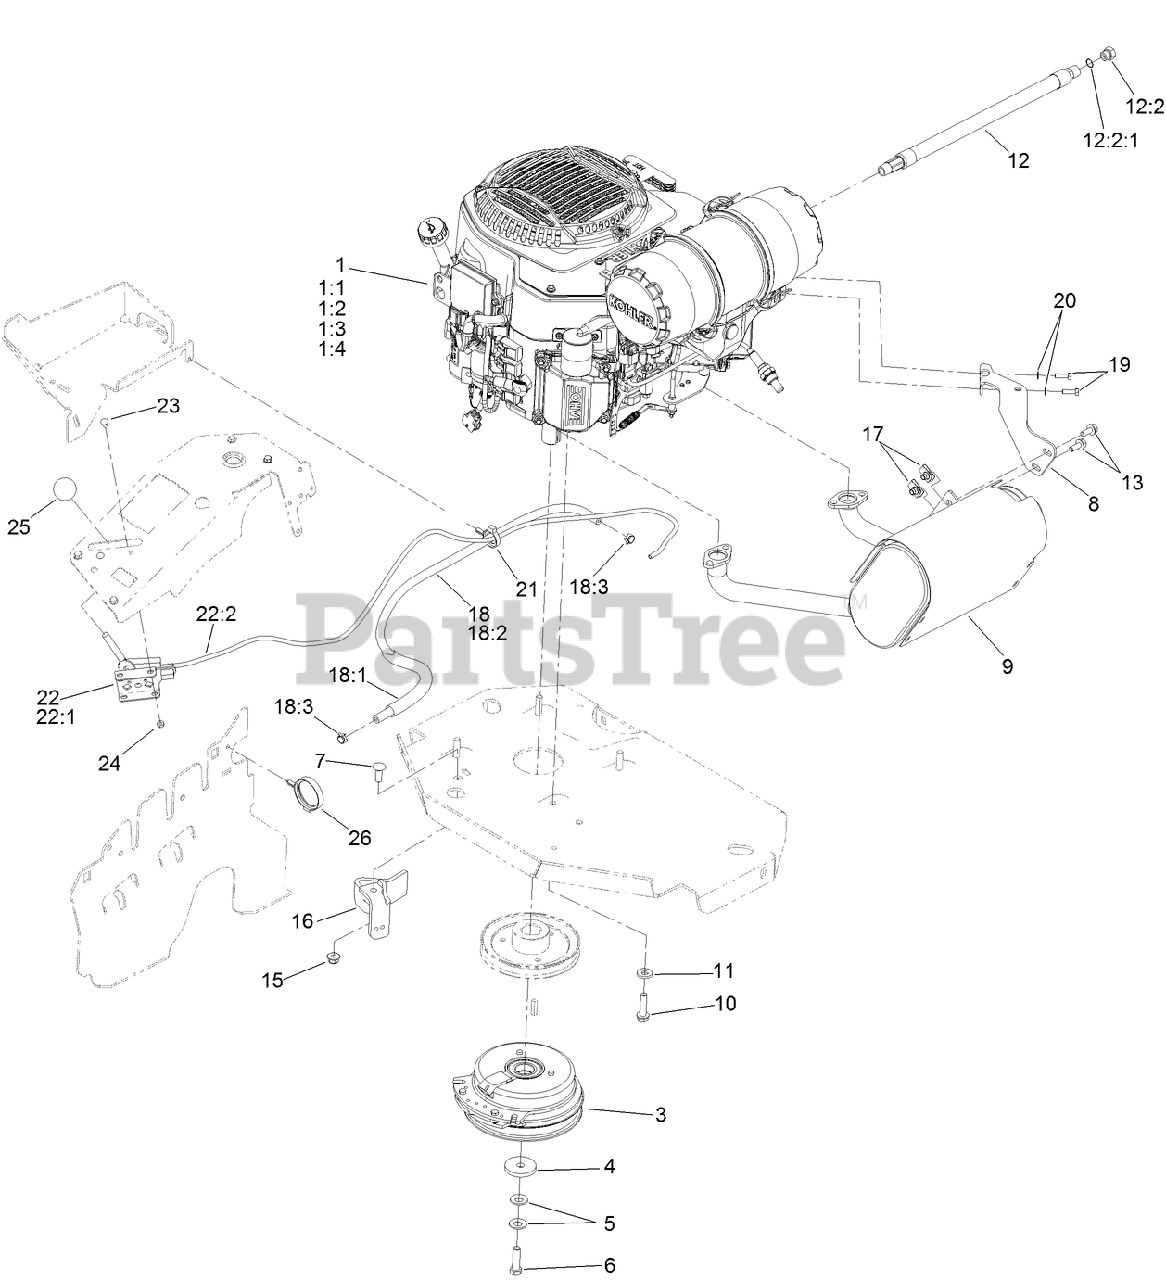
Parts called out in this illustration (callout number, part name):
1:1	KOHLER 52 050 02-S ENGINE OIL FILTER
1:2	KOHLER 25 083 01-S ENGINE AIR FILTER
1:3	KOHLER 25 083 04-S SAFETY FILTER
1:4	KOHLER 25 050 42-S FUEL FILTER
3	CLUTCH KIT
4	WASHER-CLUTCH
5	WASHER-SPRING
6	SCREW-HH, W/LOCTITE
7	SCREW-CARR
8	MUFFLER BRACKET KIT
9	MUFFLER KIT
10	SCREW-HWH
11	WASHER-BELLEVILLE
12	OIL DRAIN HOSE ASM
12:2	PLUG-HH
12:2:1	O-RING
13	SCREW-HH
15	NUT-HF, NI
16	CLUTCH-ANCHOR
17	NUT-U
18	FUEL LINE ASM
18:1	HOSE-FUEL
18:2	SLEEVE-THERMAL
18:3	CLAMP-HOSE
19	SCREW-HH
20	WASHER-SPRING
21	CLAMP-HOSE
22	THROTTLE CONTROL ASM
22:1	LEVER-THROTTLE
23	BOLT-CARR
24	NUT-LOCK, NI
25	KNOB-BALL
26	CLAMP-HARNESS
